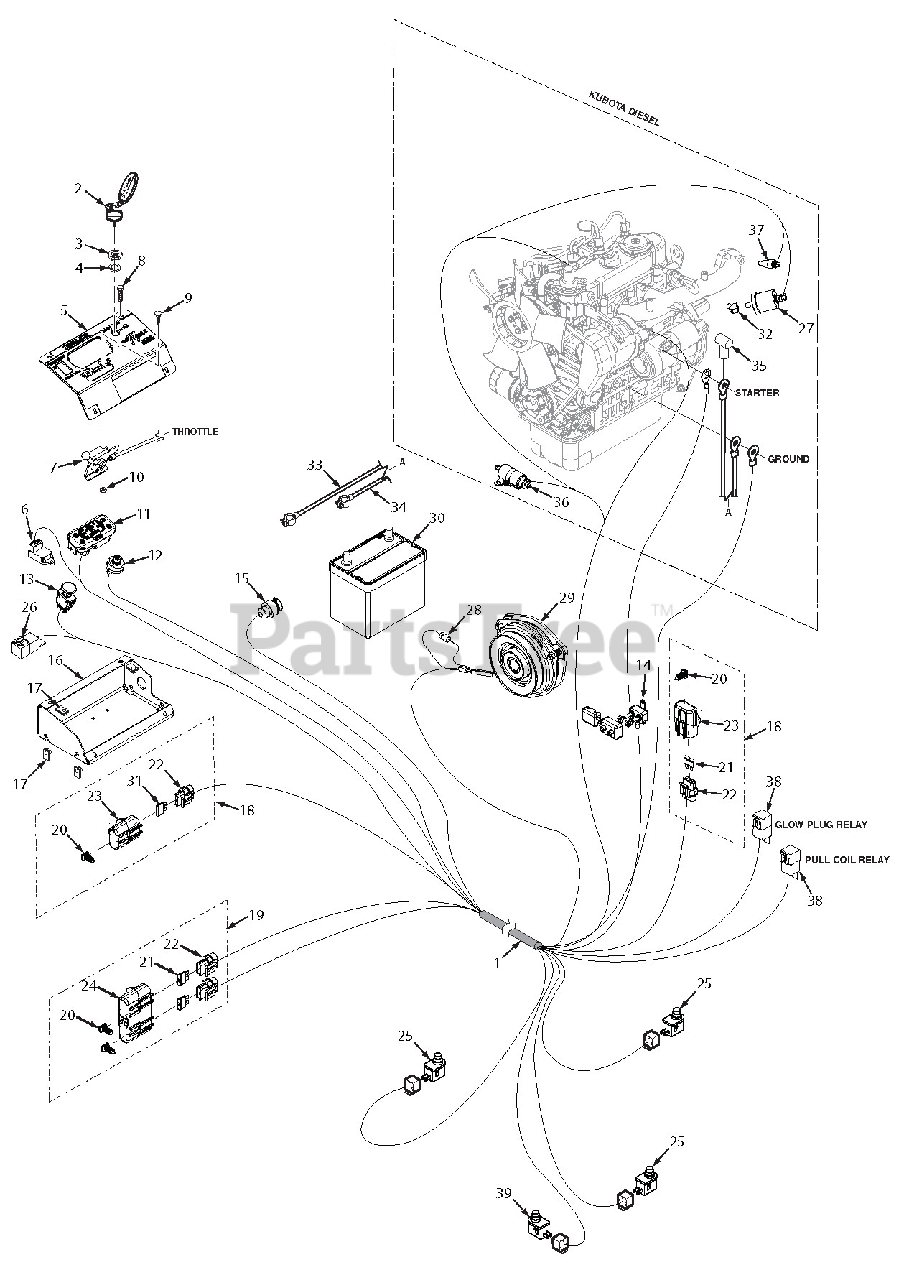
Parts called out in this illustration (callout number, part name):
1	Wire Harness, STTII-25KBD
2	Key, Ignition
2	Key Assy., w/Fob
3	Nut, Hex 5/8-32
4	Lockwasher, 5/8 Internal
5	Instrument Panel w/Decal
6	Timer, Glow Plug
7	Control Cable, Throttle
8	Capscrew, 1/4-20 x 3/4"
9	Bolt, Carriage 10-24 x 1/2"
10	Lock Nut, #10-24
11	Cluster Gauge
12	Key Switch
13	Switch, PTO
14	50 Amp Breaker
15	Power Plug, 12V
16	Base, Instrument Panel
17	U-Nut, 1/4-20
18	Single Fuse Assy., Excluding Fuse
19	Double Fuse Assy.
20	Clip, Wire
21	Fuse, 20 Amp
22	Fuse Holder
23	Cover, Sealed Single
24	Cover, Sealed Double
25	Switch, N/O
26	Relay
27	Sender Unit, Oil Pressure
28	Diode, 600V - 6A
29	Clutch Assembly, GT3.5
30	Battery, 525 CCA
31	Fuse, 5 Amp
32	Elbow, 45 Degree Street
33	Battery Cable, 14" Red w/Braid
34	Battery Cable, 21" Black
35	Rubber Boot
36	Solenoid, Fuel Shut-Off
37	Sender Unit, Water Temp.
38	Relay
39	Plunger Switch, Single Pole
